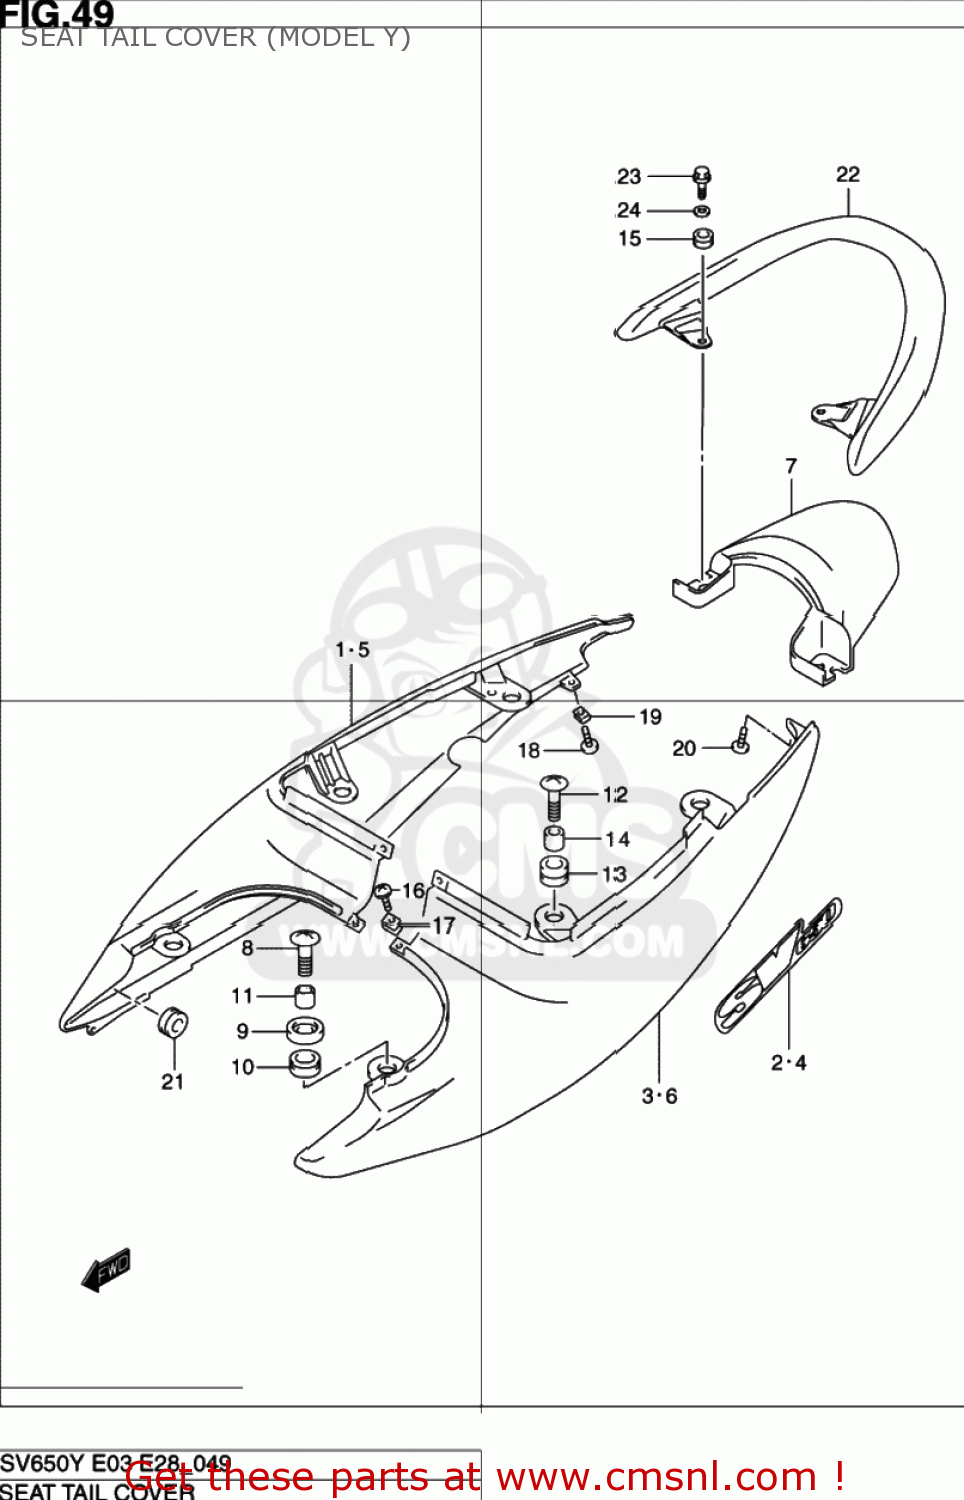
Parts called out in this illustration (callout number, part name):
1	COVER,SEAT TAIL,R(RED)
2	EMBLEM,SEAT TAIL COVER
3	COVER,SEAT TAIL,L(RED)
4	EMBLEM,SEAT TAIL COVER
5	COVER,SEAT TAIL,R
6	COVER,SEAT TAIL,L(BLUE)
7	COVER,SEAT TAIL CTR
8	SCREW(6X30)
9	CUSHION,SEAT TAIL FR UPR
10	CUSHION,SEAT TAIL COVER FR
11	SPACER(6.5X10X15.7)
12	SCREW(6X20)
13	CUSHION
14	SPACER(6.5X10X9.4)
15	CUSHION,SEAT TAIL COVER RR
16	SCREW
17	NUT
18	SCREW
19	NUT
20	SCREW
21	CUSHION
22	HANDLE,PILLION RIDER(BLACK)
23	BOLT
24	WASHER(8.5X20X2.6)
